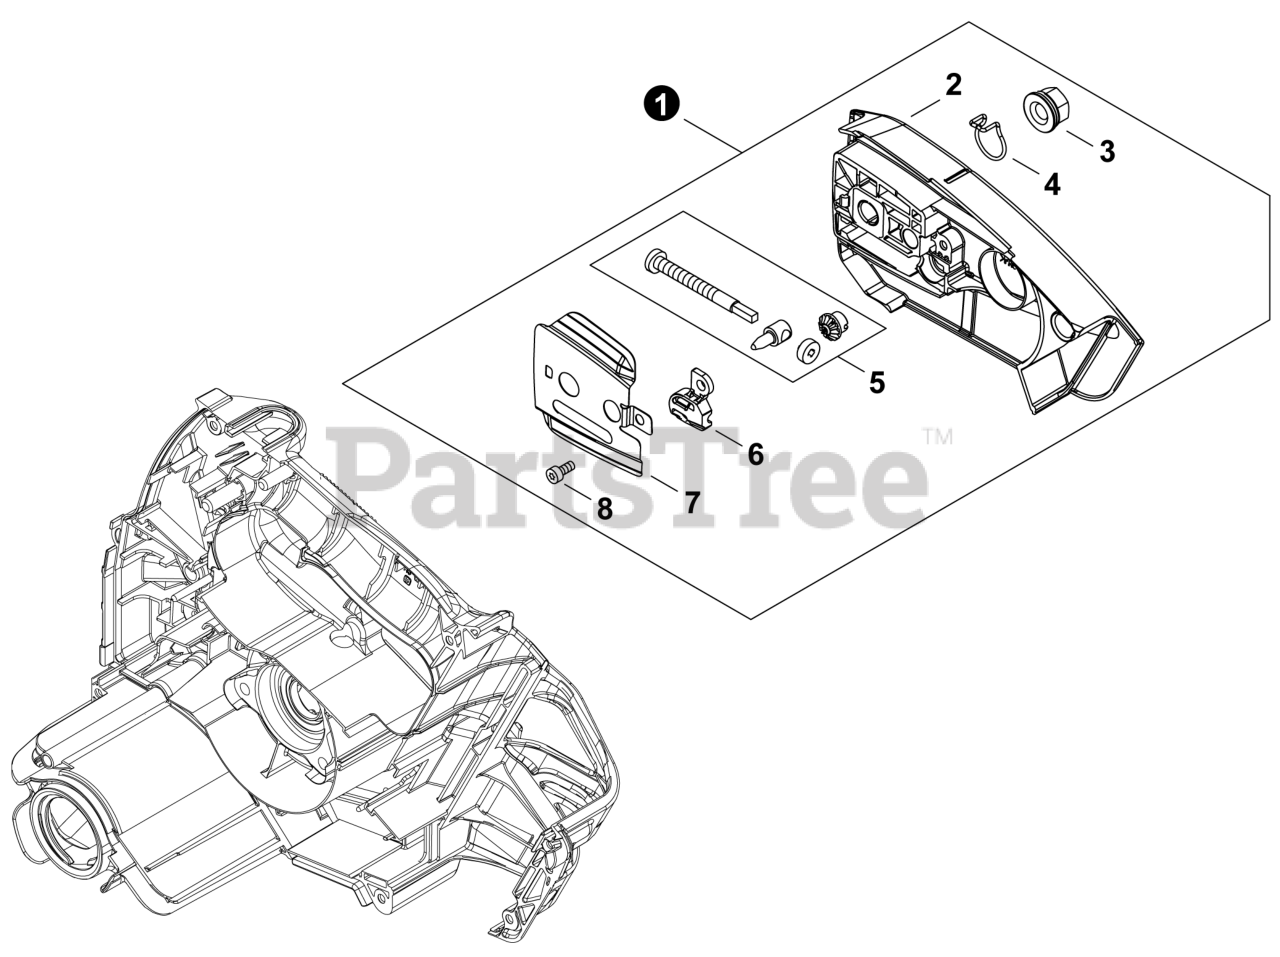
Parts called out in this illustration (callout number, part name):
1	SPROCKET GUARD ASSY
2	GUARD, SPROCKET
5	TENSIONER KIT, CHAIN
6	COLLAR 8
7	PLATE, GUIDE - OUTER
8	BOLT, TORX 4x12
